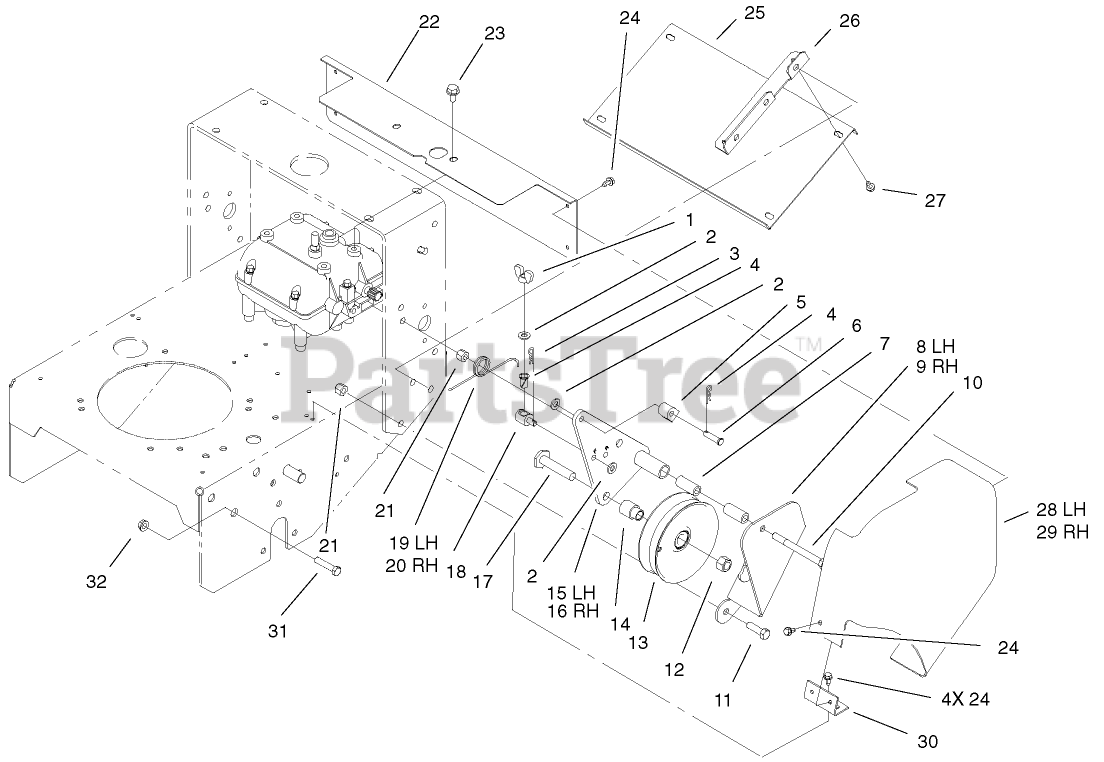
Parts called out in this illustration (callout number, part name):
1	NUT-WING
2	WASHER-PLAIN
3	PIN-COTTER
4	BUSHING-NYLON
5	FITTING-ROD
6	PIN-CLEVIS
7	SPACER-PIVOT, IDLER
8	BRACKET-SUPPORT, LH
9	BRACKET-SUPPORT, RH
10	SCREW-HH
11	SCREW-HH
12	NUT-LOCK, NI
13	PULLEY-IDLER
14	SPACER-PULLEY
15	BRACKET-IDLER, LH
16	BRACKET-IDLER, RH
17	SCREW-LEVELER
18	FITTING-ROD
19	SPRING-TORSION, LH
20	SPRING-TORSION, RH
21	NUT-LOCK, NI
22	GUARD-SHAFT, TRANSMISSION
23	SCREW-HWHTF
24	SCREW
25	PANEL-BOTTOM
26	ANGLE-MOUNTING
27	SCREW
28	Guard-Belt, LH
29	Guard-Belt, RH
30	MOUNT-BELT GUARD
31	SCREW-HHF
32	NUT-HF
